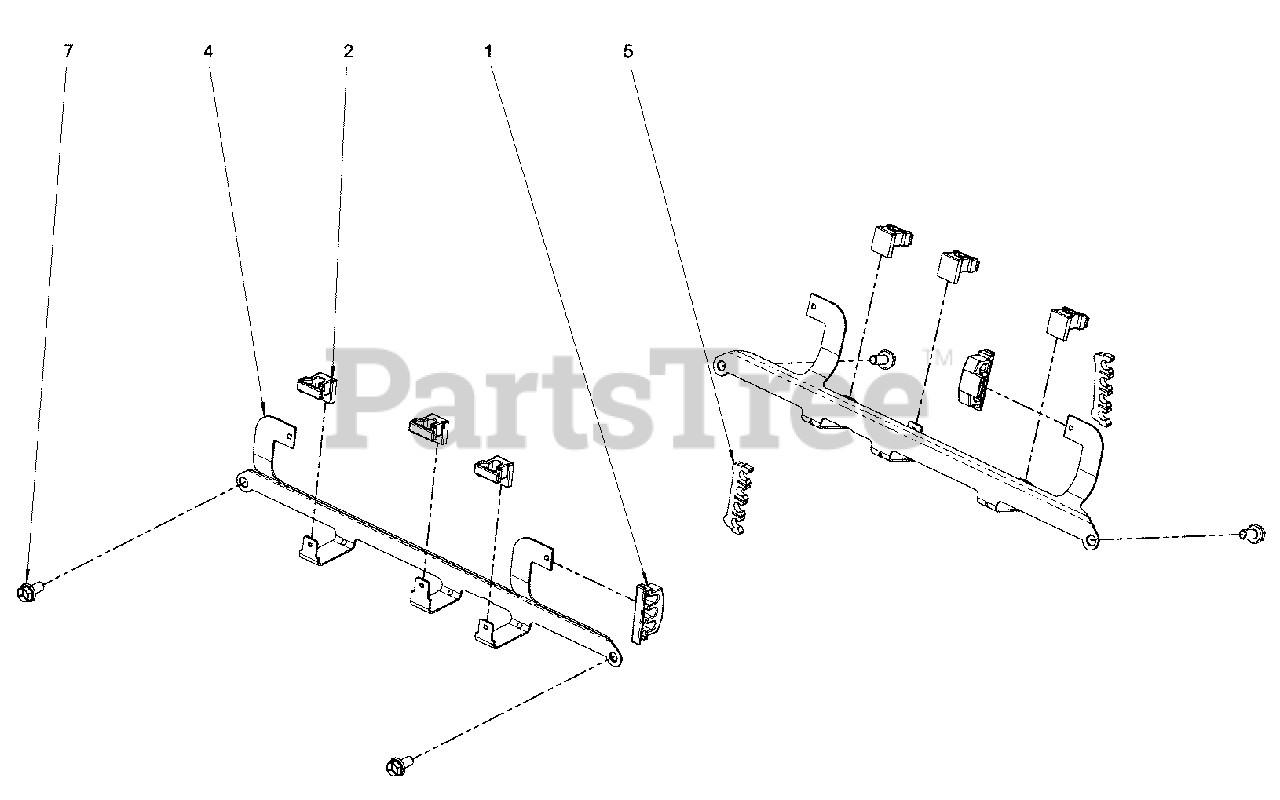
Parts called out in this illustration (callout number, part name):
1	RETAINER, WIRE #3
2	RETAINER, WIRE #1
4	SUPPORT, S/P WIRE
5	RETAINER, WIRE #4
7	BOLT
